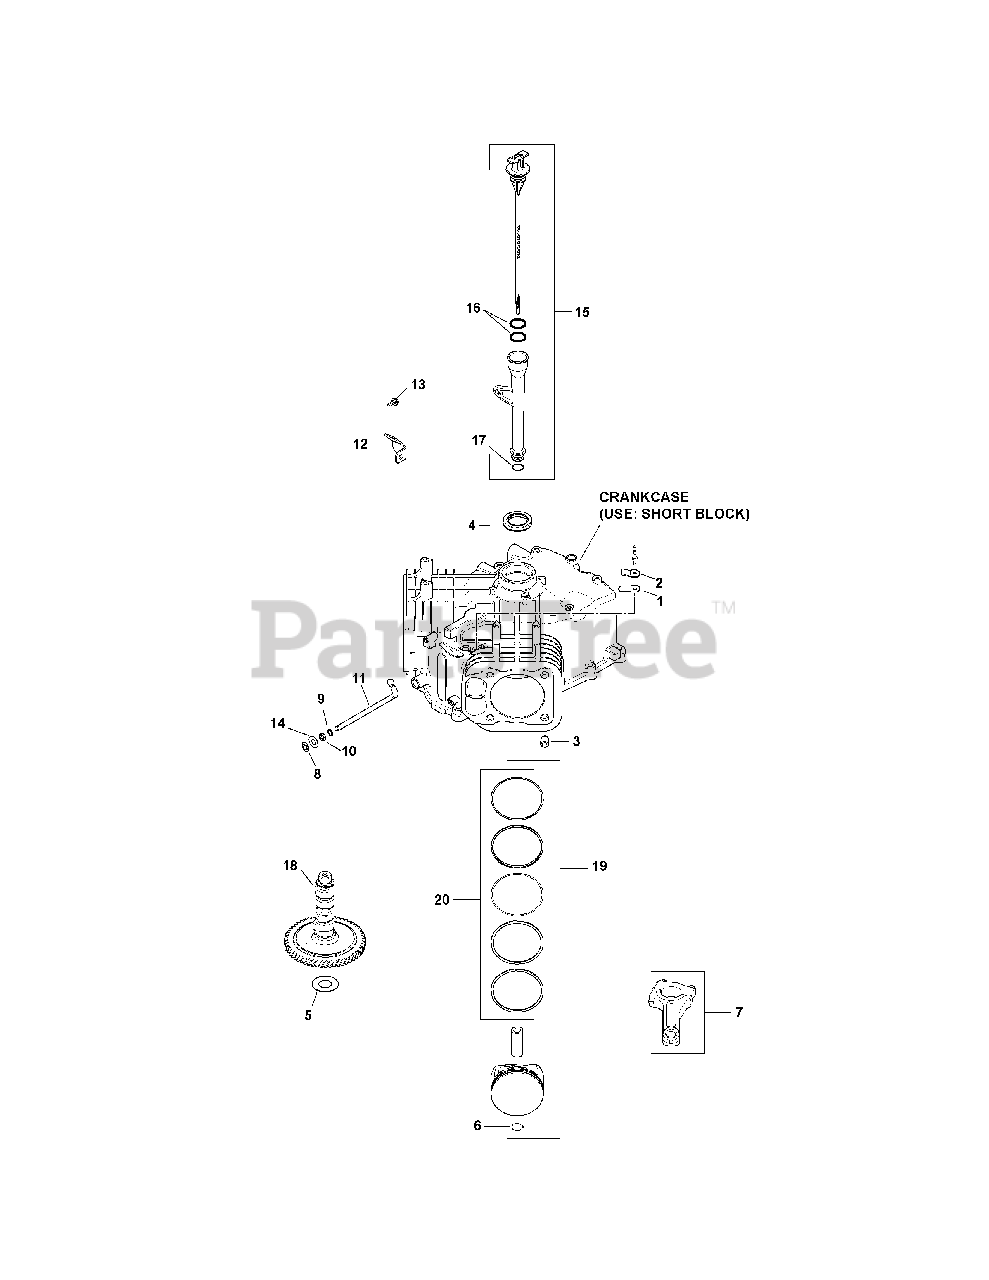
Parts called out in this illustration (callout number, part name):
1	Breather Reed
2	Breather Reed Retainer
4	Oil Seal (Helix Lip)
5	Camshaft Shim (White .028")
5	Camshaft Shim (Blue .03")
5	Camshaft Shim (Red .032")
5	Camshaft Shim (Yellow .034")
5	Camshaft Shim (Green .036")
5	Camshaft Shim (Gray .038")
5	Camshaft Shim (Black .04")
6	Piston Pin Retainer
7	Connecting Rod (Std)
8	Ring Retainer
9	Flat Washer, 11/32
10	Governor Cross Shaft Seal
11	Governor Cross Shaft
12	Oil Fill Tube Bracket
13	Flg. Thd. Frm. Screw, M5 x 0.8 x 13
14	Flat Washer, 9mm
15	Dipstick And Tube Kit
16	Dipstick O-Ring
17	O-Ring, Lower Oil Fill Tube
18	Camshaft Assembly
19	Piston Kit w/ Ring
19	Piston Kit w/ Ring (0.25) 83mm
19	Piston Kit w/ Ring (0.08) 83mm
20	Ring Set, Piston STD
20	Ring Set, Piston (.08)
20	Ring Set, Piston (.25)
